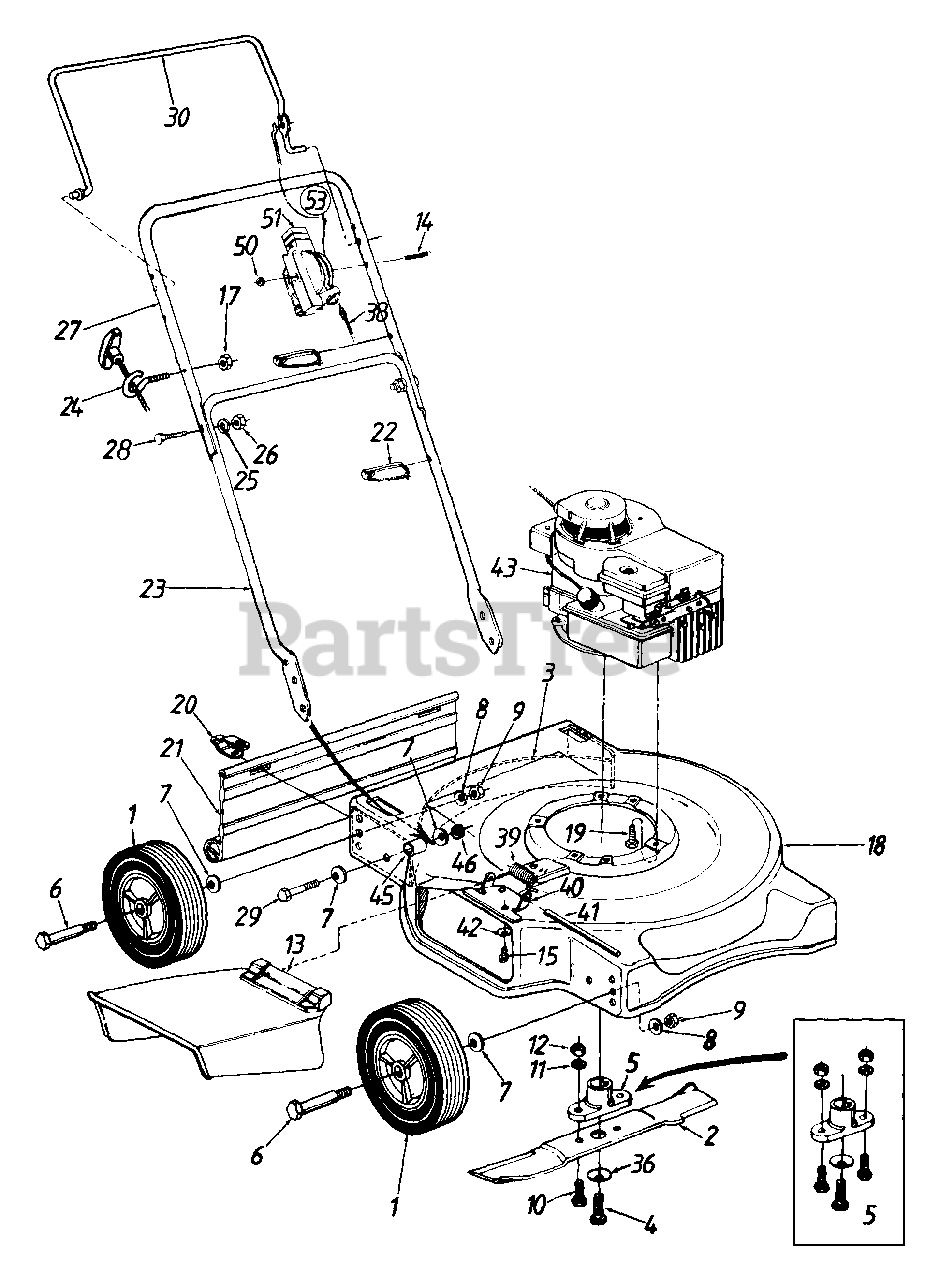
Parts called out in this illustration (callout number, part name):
1	Wheel Ass'y. Complete
2	20" Blade
5	Blade Adapter Kit
6	Axle Bolt
7	Bell-Wash. .380" I.D. x .88"
8	Bell-Wash. .39" I.D. x 1.13"
9	Hex Nut 3/8-16 Thd.
10	Hex Bolt 3/8-24 x 1" Lg.
11	L-Wash. 3/8" I.D.
12	Hex Nut 3/8-24 Thd.
13	Chute Deflector Ass'y.
14	Oval C-Sunk Scr.
15	Self-Tap Scr. 1/4-20 x .5" Lg.
17	Hex L-Nut 1/4-20 Thd.
20	Hinge Clip
21	Rear Flap 16.69" Lg.
22	Cable Tie
24	Rope Guide
25	L-Wash. 5/16" I.D.
26	Hex Nut 5/16-18 Thd.
27	Upper Handle
28	Curved Carriage Bolt 5/16-18 x 1.38" Lg.
29	Hex Bolt 3/8-24 x 1.5" Lg.
30	Control Handle
36	Bell-Wash. .39" I.D.
38	Control Cable - 36"
39	Torsion Spring
40	Adapter Plate
41	Hinge Pin
42	Bell-Wash. 1/4" I.D.
43	Engine
45	Spacer
46	Hex L-Nut 3/8-24 Thd.
50	Hex L-Nut 1/4-20 Thd.
51	Throttle Body
53	Throttle Box Comp.
